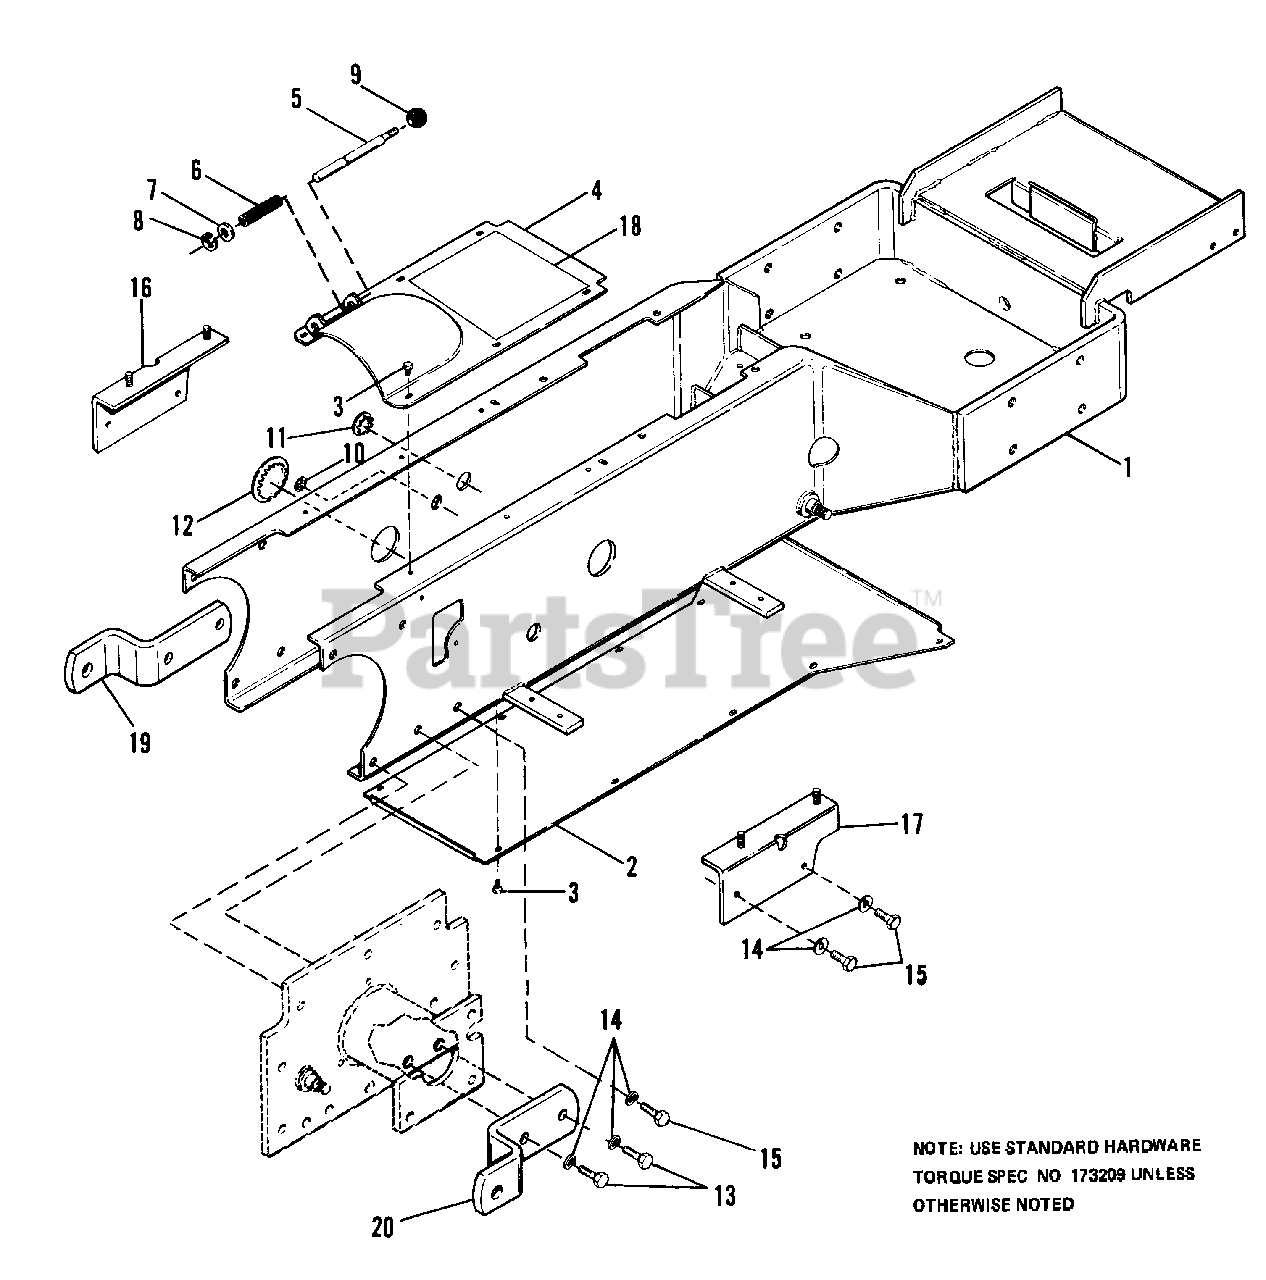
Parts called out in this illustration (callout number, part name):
1	FRAME ASSY
2	COVER, Bottom
3	SCREW, Washer, Taptite, 1/4-20 x 3/4
4	COVER ASSY
8	RING, Retaining
10	PLUG, Hole
11	PLUG, Hole
12	PLUG, Hole
13	CAPSCREW, Hex, 1/2-13 x 2
14	LOCKWASHER, 1/2
15	CAPSCREW, Hex, 1/2-13 x 1-1/2
16	SUPPORT ASSY, Seat, L.H.
17	SUPPORT ASSY, Seat, R.H.
18	DECAL, Shift & Safety
19	STRAP, Pull Link, L.H. (Used on 1690230 Only)
20	STRAP, Pull Link, R.H. (Used on 1690230 Only)
